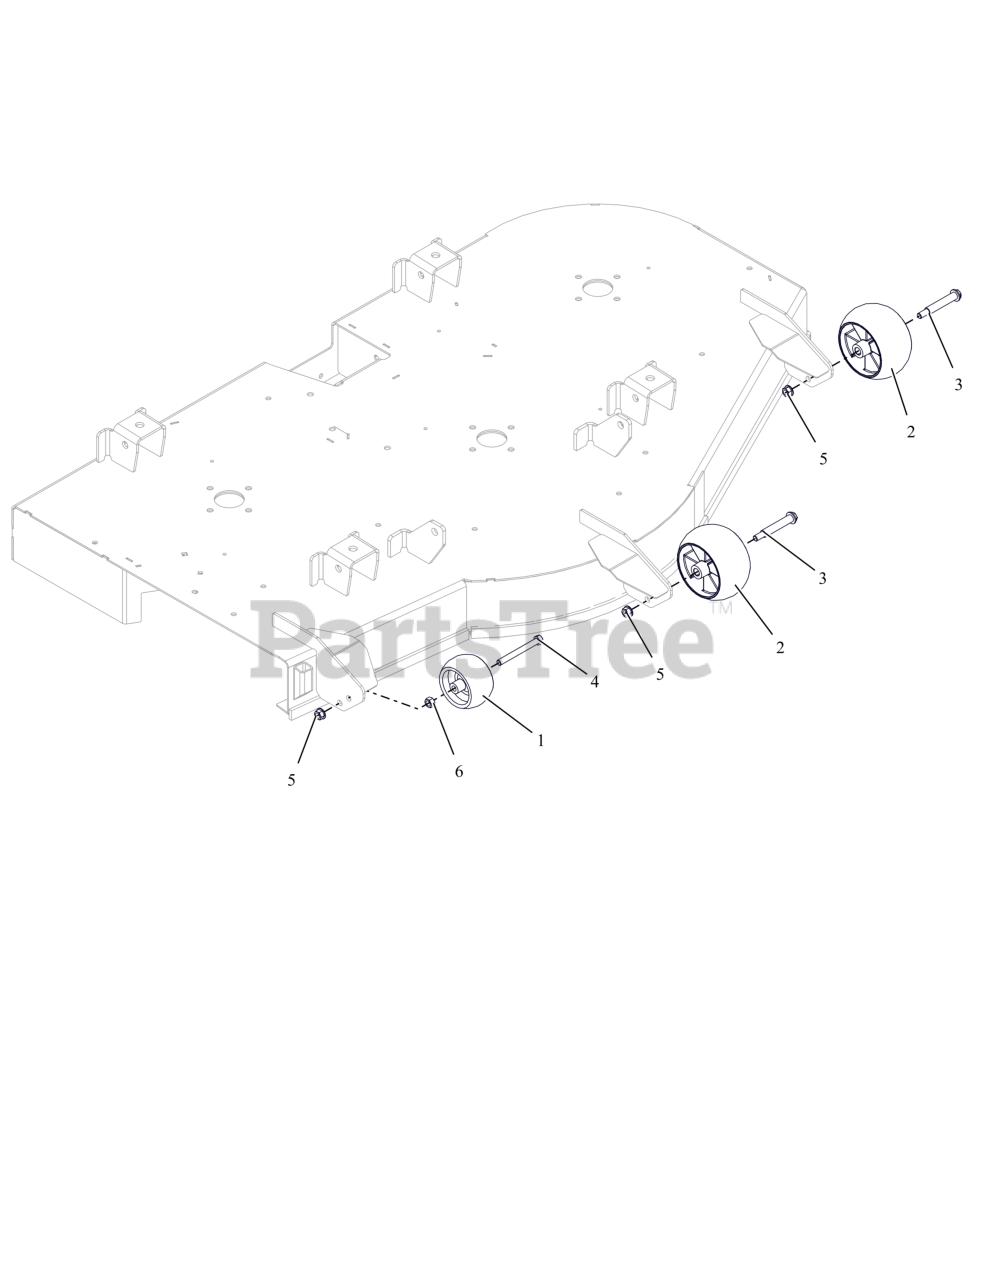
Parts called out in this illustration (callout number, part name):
2	ANTI-SCALP WHEEL - 5X OS
3	BLT-SHLDR .38-16X2.50 HWH G5
4	BLT, HEX .38-16X3.50 G5 ZCC
5	NUT-LK-CTR-FLG .375-16 GF ZCC
6	NUT-STD .375-16 G2 ZCC
